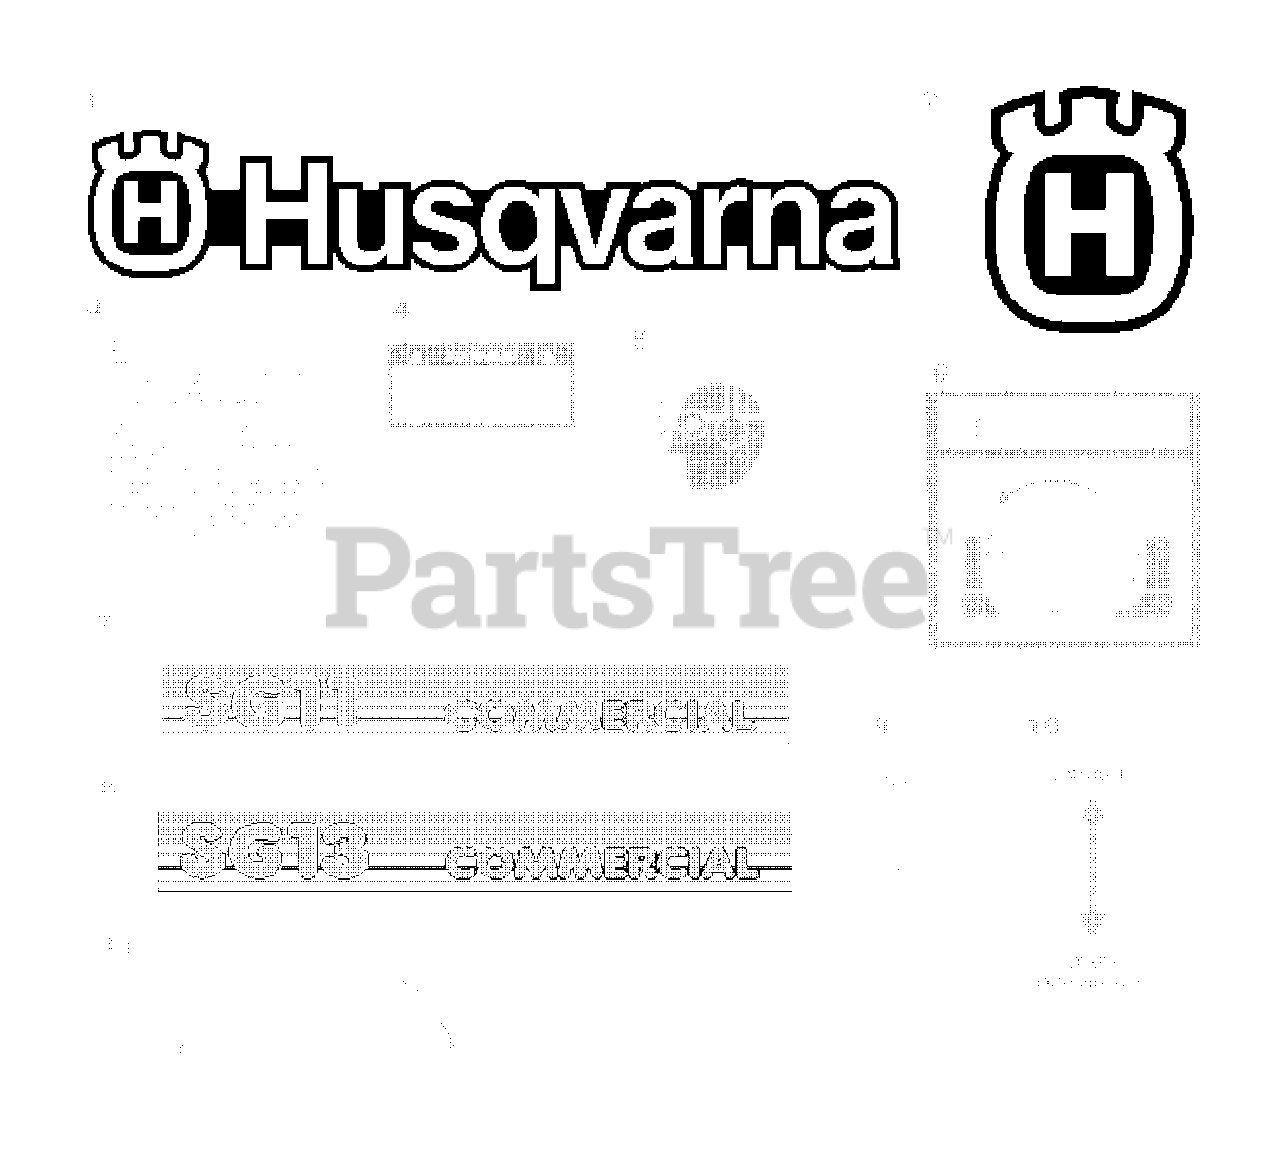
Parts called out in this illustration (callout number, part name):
1	Decal, Husqvarna logo and crown
2	Decal, Crown
3	Decal, Caution list
4	Decal, Warning Carbon monoxide
5	Decal, Eye and hearing
6	Decal, Danger foot
9	Decal, On/Off toggle
10	Decal, Throttle control
11	Decal, Handle adjustment
12	Decal, Nascar
